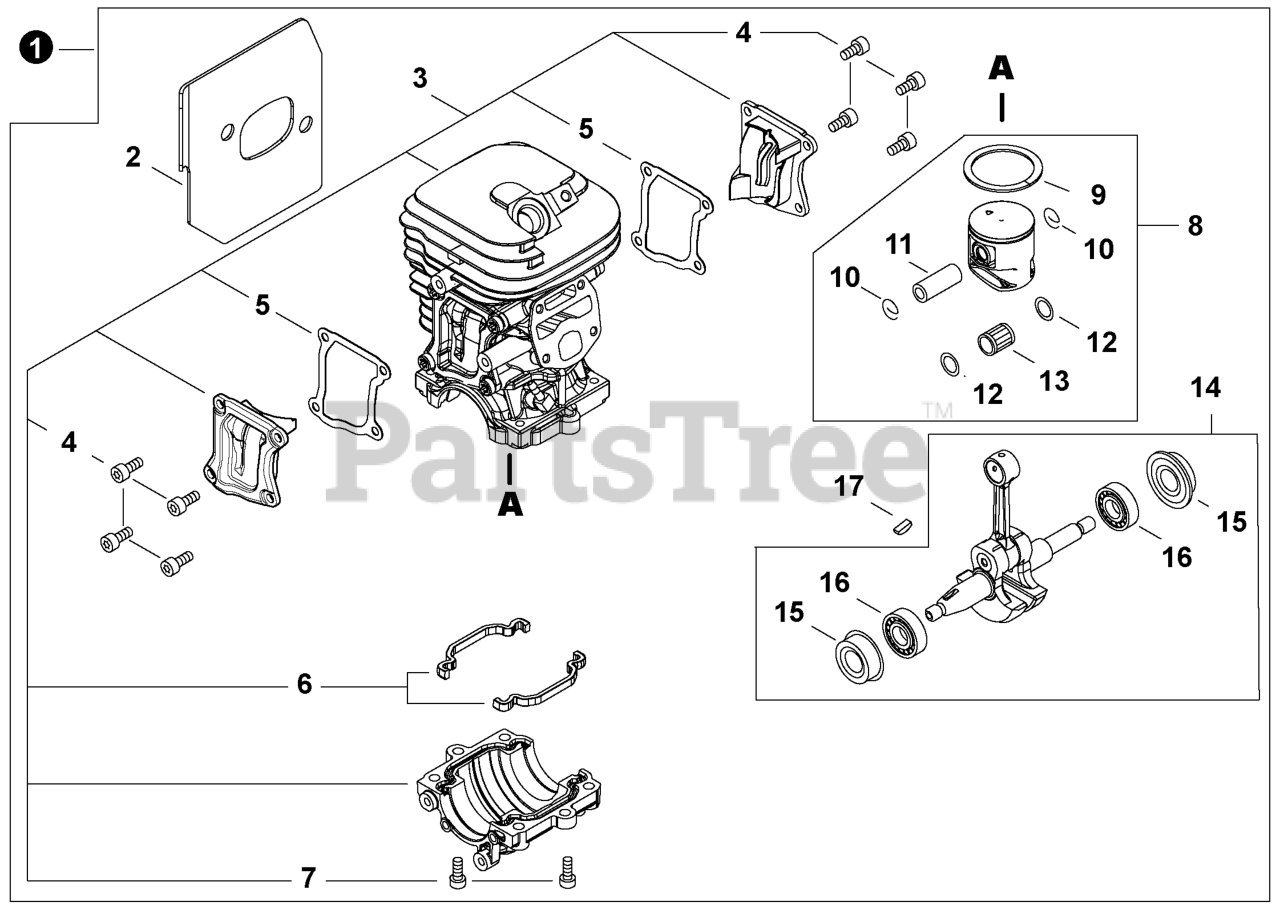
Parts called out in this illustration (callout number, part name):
1	SHORT BLOCK
2	GASKET, EXHAUST
3	CYLINDER ASSY
4	BOLT, TORX 4x10
5	GASKET
6	SEAL KIT
7	BOLT, TORX 5x16
8	PISTON KIT
9	RING, PISTON
10	RING, SNAP 10
11	PIN, PISTON
12	WASHER, THRUST 10
13	BEARING, NEEDLE
14	CRANKSHAFT ASSY
15	SEAL, OIL
16	BEARING, BALL 6202
17	KEY, WOODRUFF
